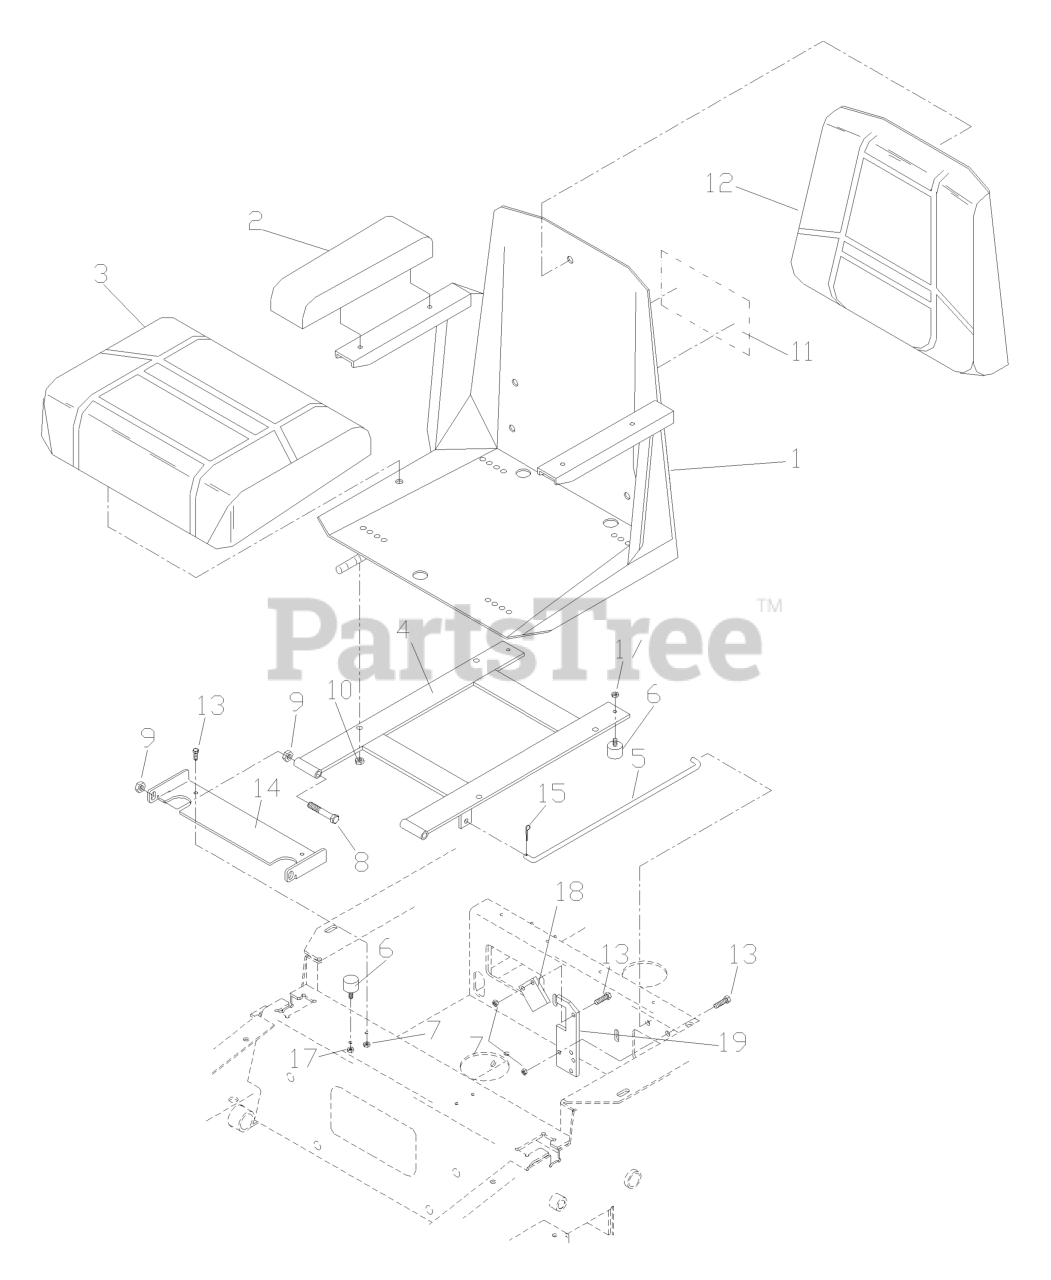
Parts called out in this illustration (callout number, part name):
1	SEAT, COMPLETE
2	ARM REST CUSHIONS/PAIR
3	SEAT CUSHION W/SWITCH
4	SEAT MOUNT
6	STUD/PLATE MOUNT
7	NUT 1/4C CENTER LOCK
8	HCS 3/8C X 3
9	NUT 3/8C CENTERBLOCK
10	NUT 5/16 NYLOC
11	DECAL, CROWN H
12	SEAT, BACK CUSHION
13	HCS 1/4C X 3/4 HCS
14	SEAT BRKT W/DECAL
15	RP_COTTER PIN 1/8 X 3/4
17	NUT.1/4-20.HEX.NYLOC.ZD
18	SEAT LATCH
19	SEAT LATCH BASE
